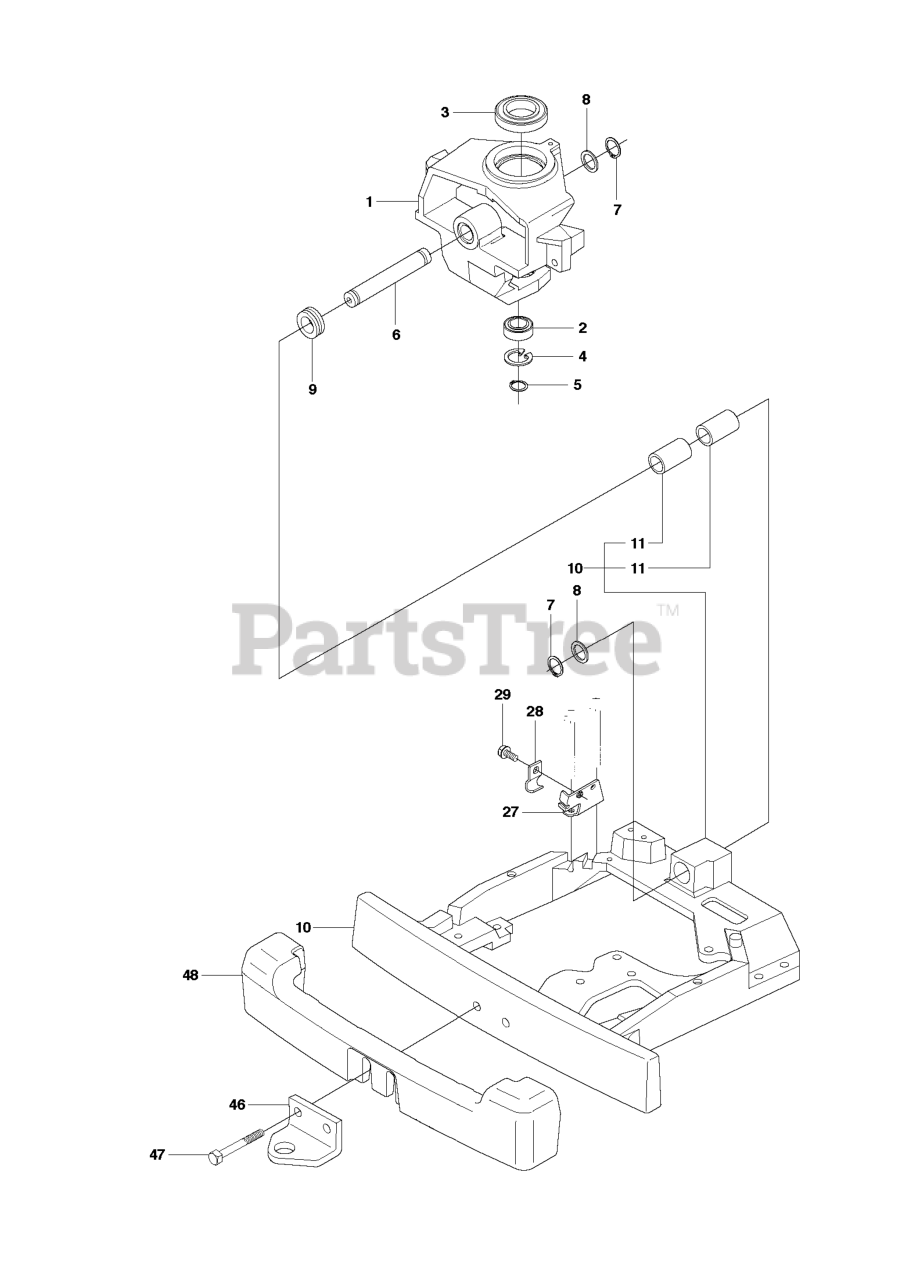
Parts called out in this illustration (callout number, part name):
2	Ball Bearing 6005-2rs
3	BALL BEARING 6010 2RS1
4	CIRCLIP SGH 47
5	RETAINING RING SGA 25
7	RETAINING RING SGA 25
47	REPL BY 725 25 00-71
48	COUNTERWEIGHT
